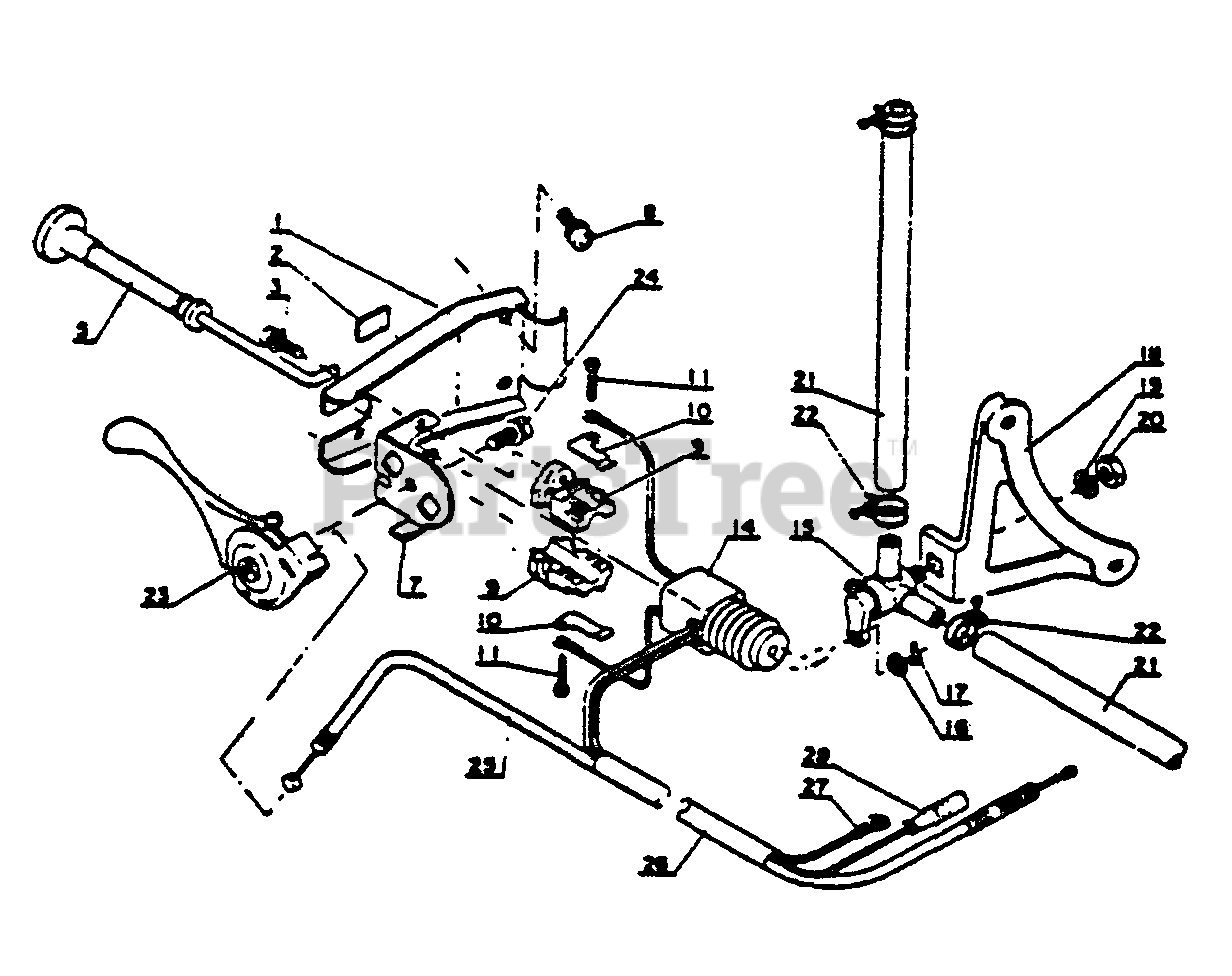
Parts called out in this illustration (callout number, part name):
1	BRACKET, SWITCH
2	LABEL - STOP
3	SCREW 4×12
5	KNOB
7	BRACKET, THROTTLE LEVER
8	SCREW - 5×10
9	BODY, SWITCH
10	PLATE, SWITCH
11	SCREW - 3×15
14	BRACKET, SWITCH
15	FUEL VALVE ASSY
16	WASHER 4 MM
18	BRACKET, FUEL VALVE
19	WASHER, SPRING 6
21	PIPE, FUEL
22	CLAMP
23	LEVER, THROTTLE
24	SCREW 5×12
25	THROTTLE CONTROL ASSY
26	THROTTLE CONTROL ASSY
27	LEAD - GROUND
28	LEAD
